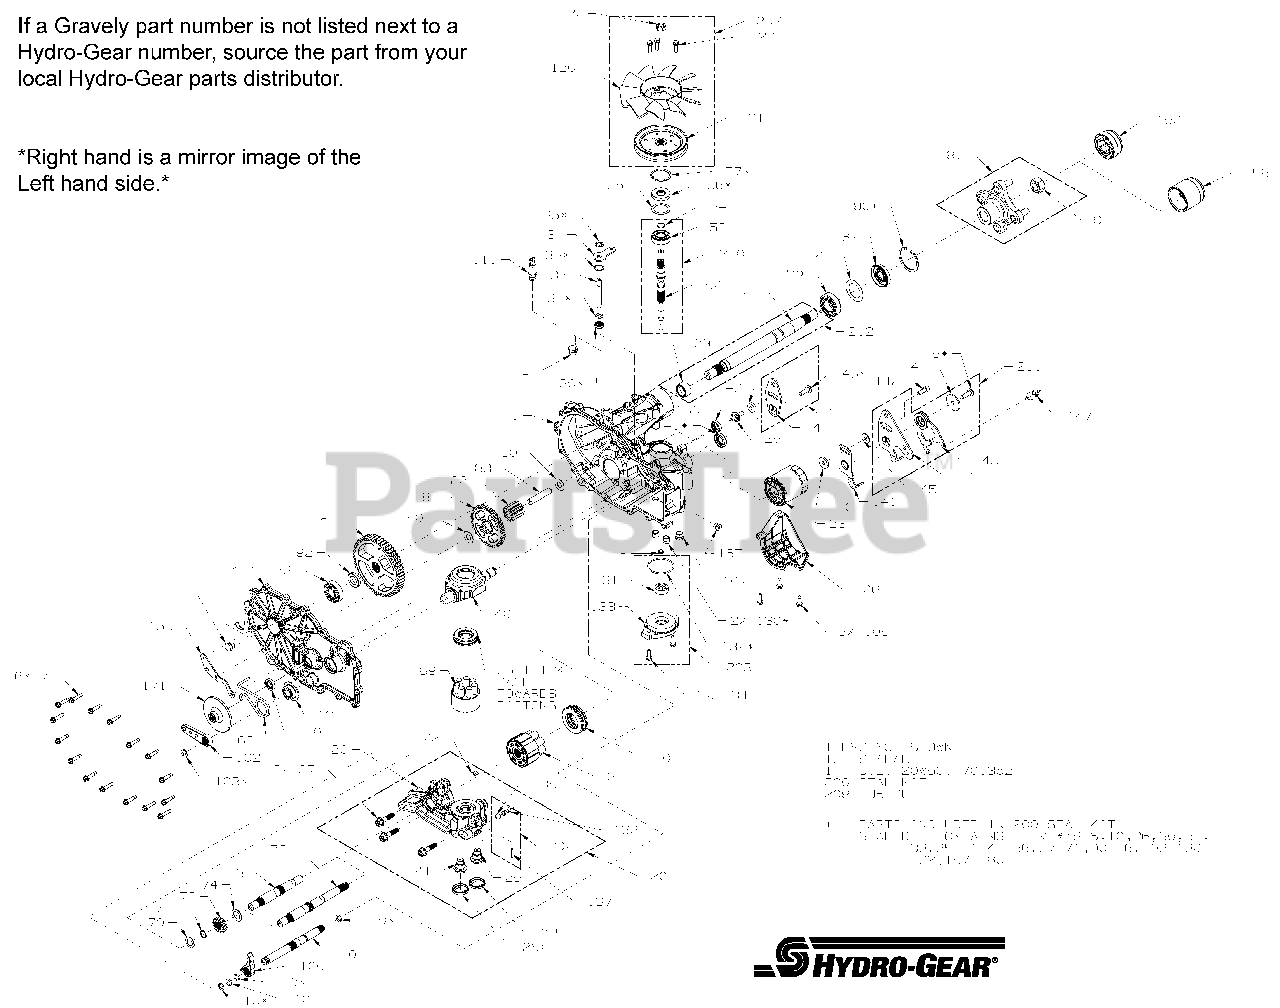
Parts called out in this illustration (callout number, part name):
7	HFHCS 1/4-20 x 1.125"
13	SEALANT, TUBE
22	PLATE, BYPASS
23	FILTER, OIL
26	SEAL, PLUG 1.250 X .250
30	SEAL, LIP .375 X .75 X .25
31	RING, RETAINING .375 EXTERNAL
33	RING, RETAINING .750 INTERNAL
34	ARM, BYPASS
35	RING, RETAINING .375 EXTERNAL
40	TRUNNION, SWASHPLATE
41	SEAL, LIP 12 X 32 X 7
45	WASHER, .34 X .88 X .06
46	TWHCS 5/16-24 X 1.00
55	WASHER, 1.23 X 1.56 X .04
56	SEAL, LIP 17 X 40 X 7
57	RING, RETAINING
60	BEARING, THRUST
64	KIT, 16cc MOTOR BLOCK
65	BEARING, THRUST BALL 30 X 52 X 13
69	ASS'Y, BLOCK 7 PISTON
70	WASHER, .63 X 1.0 X .05
71	RING, RETAINING .625
74	WASHER, .72 X 1.16 X .04
80	WASHER, .5 X 1.0 X .03
83	JACK SHAFT
90	RING, RETAINING 2.06 INTERNAL
95	BEARING, BALL 1.0 X 52 X 15 OPEN 6205M
96	SEAL, LIP TC4, 1.0 X 2.06 X .38
97	KIT, HUB, 5 BOLT
99	NUT, HEX LOCK 3/4-16
102	KIT, BRAKE ARM RIGHT HAND
105	HFHCS 1/4-20 X .75
106	GUARD, FILTER, RH
111	FITTING, STR 9/16-18 SAE .5 BARB
122	NUT, HEX JAM 1/2-20 W/ PATCH
131	GEROTOR ASSEMBLY
132	O-RING, -.137, .103 X 2.050
134	HFHCS 1/4-20 X .75
140	SPACER, .320 X 1.005 X .179
141	ARM, NEUTRAL RIGHT
142	SHCS 5/16-24 X 1
200	KIT, SEAL
201	KIT, CENTERSECTION, RH, CHRG
203	KIT, CHARGE PUMP
207	KIT, FAN/PULLEY
209	HUB PULLER, UNIVERSAL
210	KIT, INPUT SHAFT
211	KIT, RTN, CW
